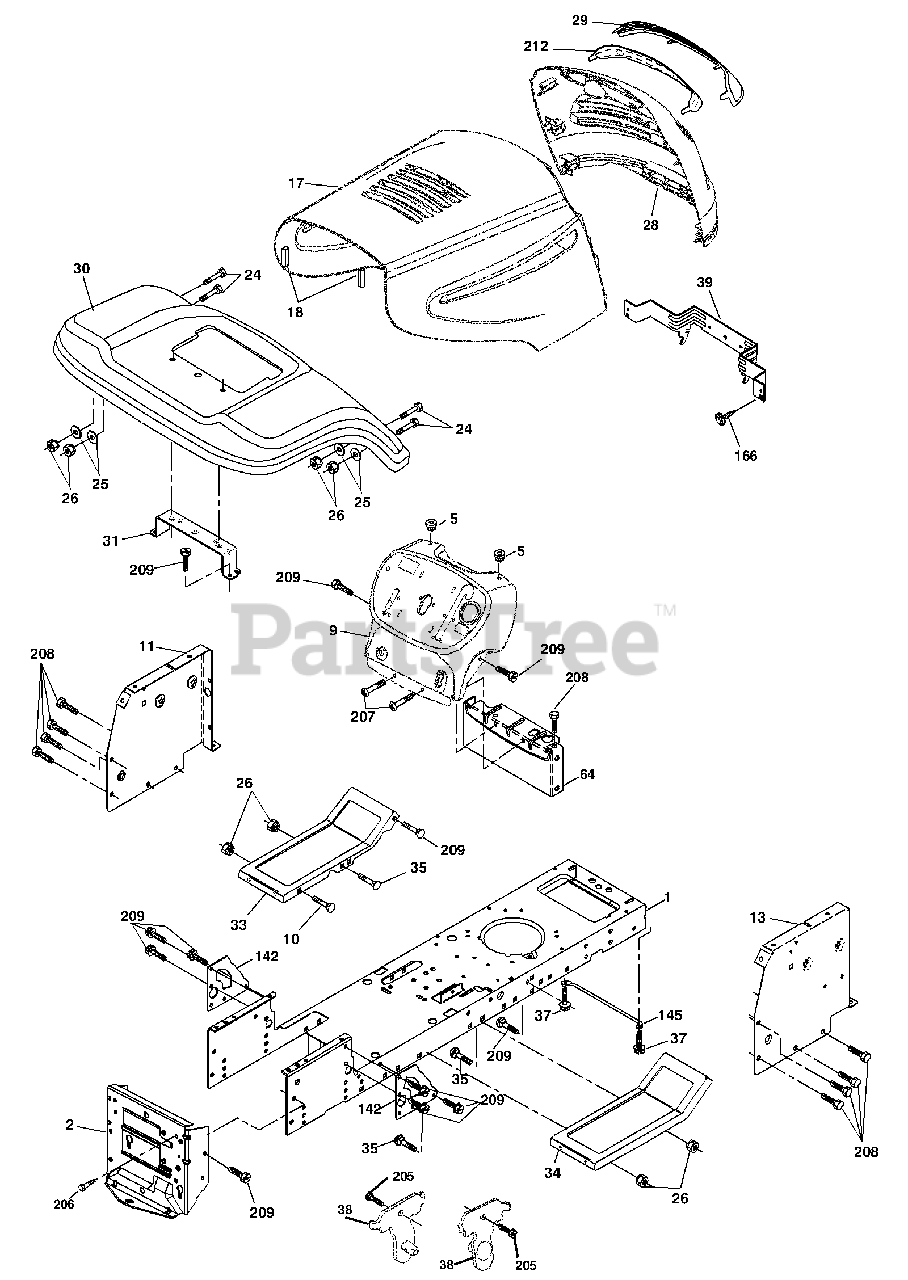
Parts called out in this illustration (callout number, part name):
1	Chassis
2	Drawbar
5	Bumper Hood/Dash
9	Dash
10	Bolt Carriage 3/8-16 x 1
11	Panel Dash Lh
17	Hood
18	Bumper Hood
24	Bolt Fin Hex 3/8-16 x 1 Gr. 5
25	Washer 13/32 x 13/16 x 12 Ga.
26	Nut Lock Hex W/Ins 3/8-16 unc
28	Grille
29	Lens
30	Fender Footrest STLT Pnt
31	Bracket Support Fender
33	Footrest Pnt Lh
34	Footrest Pnt Rh
35	Bolt Rdhd Sht Sqnk 3/8-16 x 3/4
37	Screw Thdrol 6/16-18 x 1/2 TYT
38	Bracket Asm. Pivot Mower Rear
39	Bracket Pivot
64	Dash Lower STLT
142	Plate Reinforcement STLT
145	Rod Pivot Chassis/Hood
166	Screw HWHD Hi-Lo #13-16 x 5/8
205	Screw Thdrol 3/8-16 x 1-1/4
206	Bolt Shoulder 5/16-18
207	Screw Thdrol 5/16-18 x 1/2
208	Screw Thdrol 3/8-16 x 1/2
209	Screw Hex Wsh Thdr. 3/8-16 x 3/4
212	Insert Lens Reflect
